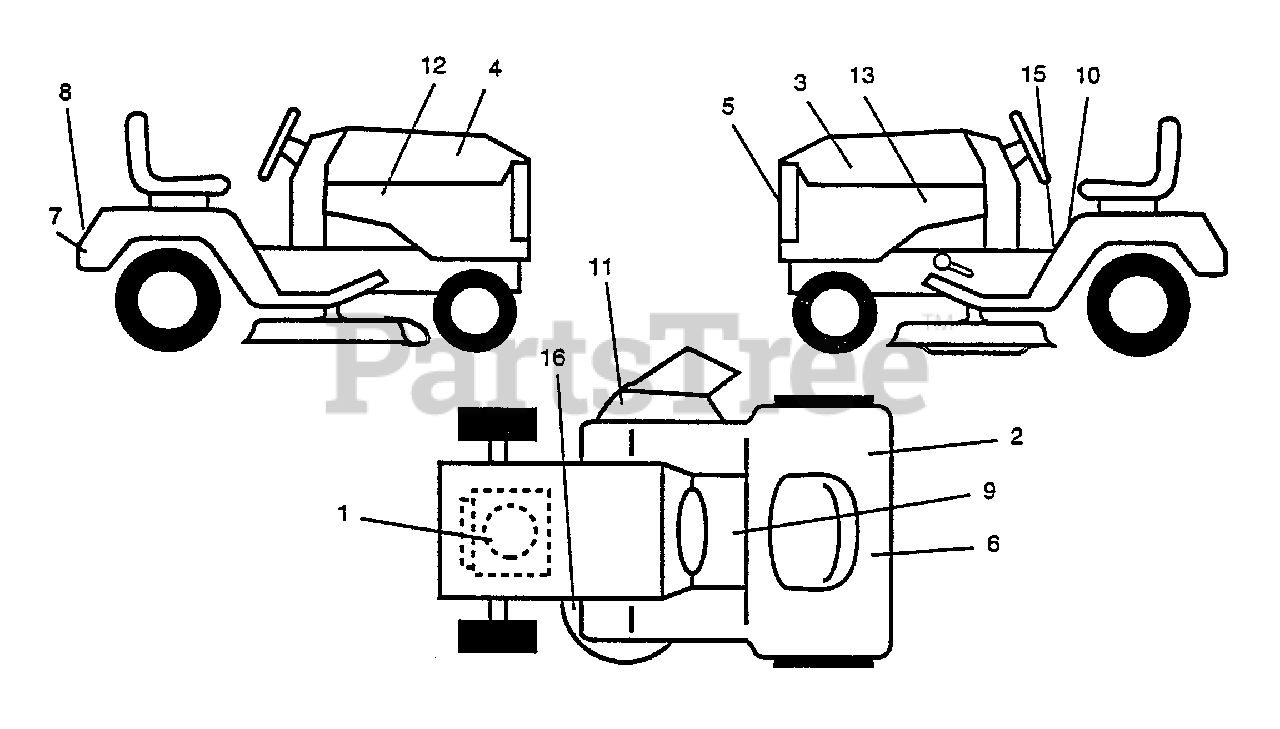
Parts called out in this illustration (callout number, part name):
1	Decal, Engine, HP
2	Decal Indicator Height
3	Decal, Hood, L.H.
4	Decal, Hood, R.H.
5	Decal, Logo, Grill
6	Decal, Caution Battery
7	Decal, Drawbar
8	Decal, Logo, Fender
9	Decal, Cold Start
10	Decal, Fender, Caution
11	Decal, Warning, Multi-Language
12	Decal, Hood, Insert, R.H.
13	Decal, Hood, Insert, L.H.
15	Decal, Instruction, Operating
16	Decal, V-Belt Schematic
CER38	Grass Catcher
